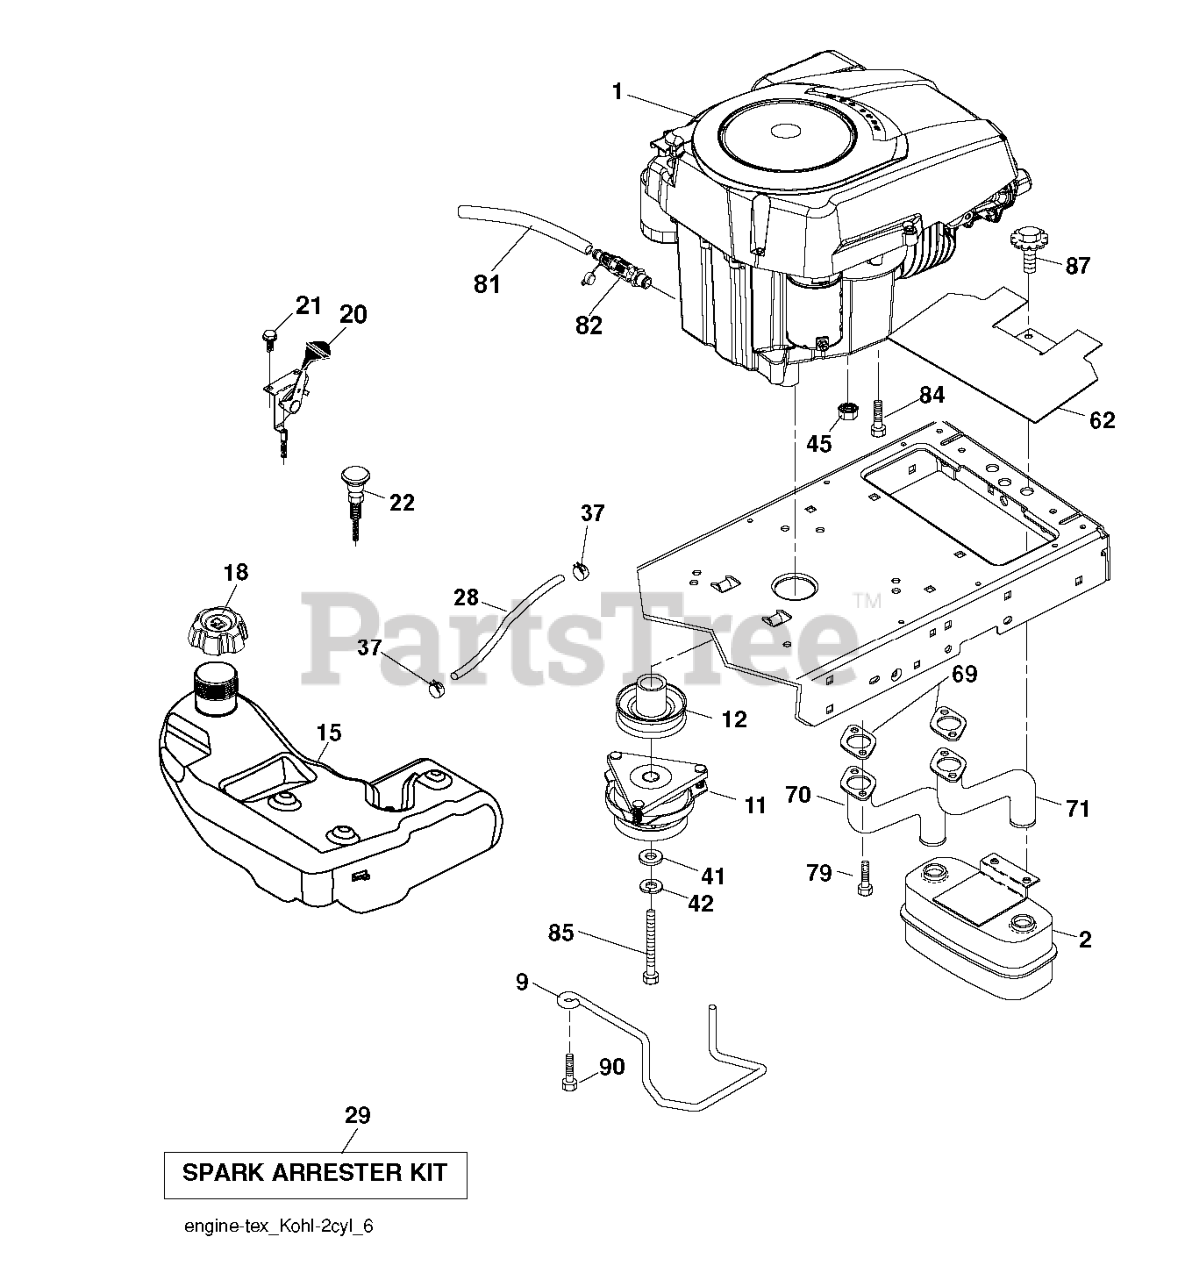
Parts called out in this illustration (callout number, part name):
2	MUFFLER.TWIN.CYL.LOW.TONE
9	KEEPER.BELT.ENGINE.4.2
11	CLUTCH MZ ZTR GT.48/54"1.125"
12	PULLEY ENGINE
15	TANK.FUEL.4GAL
18	RP CAP FUEL
20	THROTTLE CONTROL
21	SCREW.#10 X 0.750.BOS
22	CONTROL.CHOKE.ERGO.PUSH-IN.BLA
28	FUEL LINE 54"
29	KIT.SPARK ARRESTOR 794945 B&S
37	HOSE CLAMP
42	LOCKWASHER
45	NUT
62	SHIELD.HEAT.MUFFLER
69	GASKET.EXHAUST.KOHL.CV18-CV26
70	RP.PIPE-EXHAUST LH
71	RP.PIPE-EXHAUST RH
79	SCREW.SOCKET HD.5/16-1
81	TUBE, DRAIN OIL ASM.
82	VALUE.OIL.DRAIN
84	SCREW 3/8-16X1
85	BOLT HEX 7/16-20 X 3.75 GR. 5
87	BOLT.5/16-18UNCX1.W/SEMS.BLK
90	SCREW 3/8-16X1
